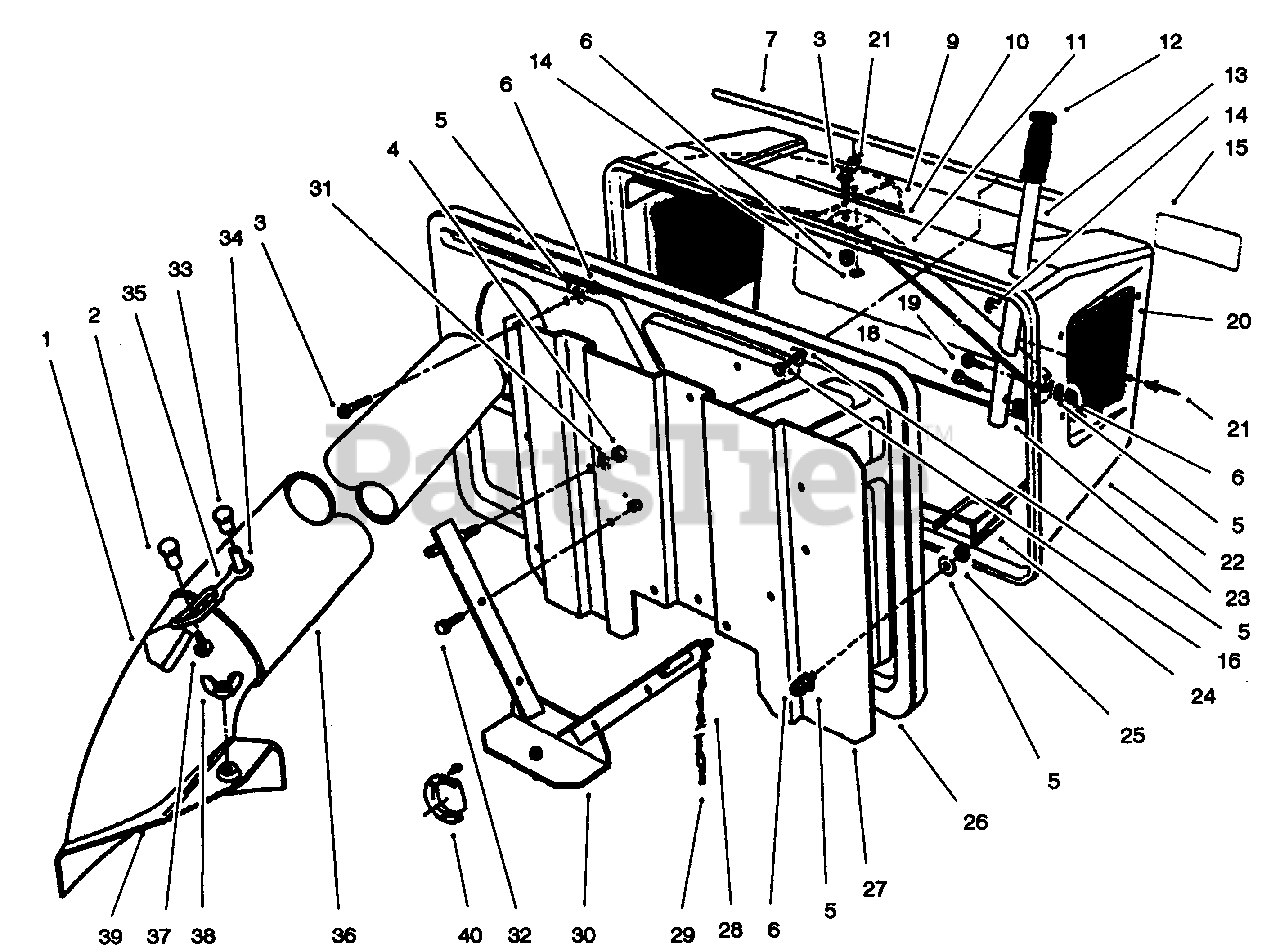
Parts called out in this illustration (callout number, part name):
1	Decal-Chute
3	Screw-Hex. Hd. Flange
4	Nut-Lock
5	Washer-Flat
6	Nut-Lock
7	Rod-Pivot
9	Deflector
10	Decal-Warning
11	Guide-Handle
12	Grip-Handle
13	Tube-Handle
14	Washer-Backup, Rivet
15	Decal-Easy Empty Bagger
16	Screw-Cap Hex. Hd.
18	Screw-Cap Hex. Hd.
19	Bolt-Carriage
21	Rivet-Pop
23	Nut-Lock
25	Nut-Hex.
27	Plate-Mounting
29	Pin-Hair, Cotter
30	V-Bracket
31	Washer-Flat
32	Screw-Cap Hex. Hd.
33	Fastner-Panel
35	Retainer-Duct
39	Chute (Incl. Ref. #1, 2 & 37)
40	Deflector-Muffler
